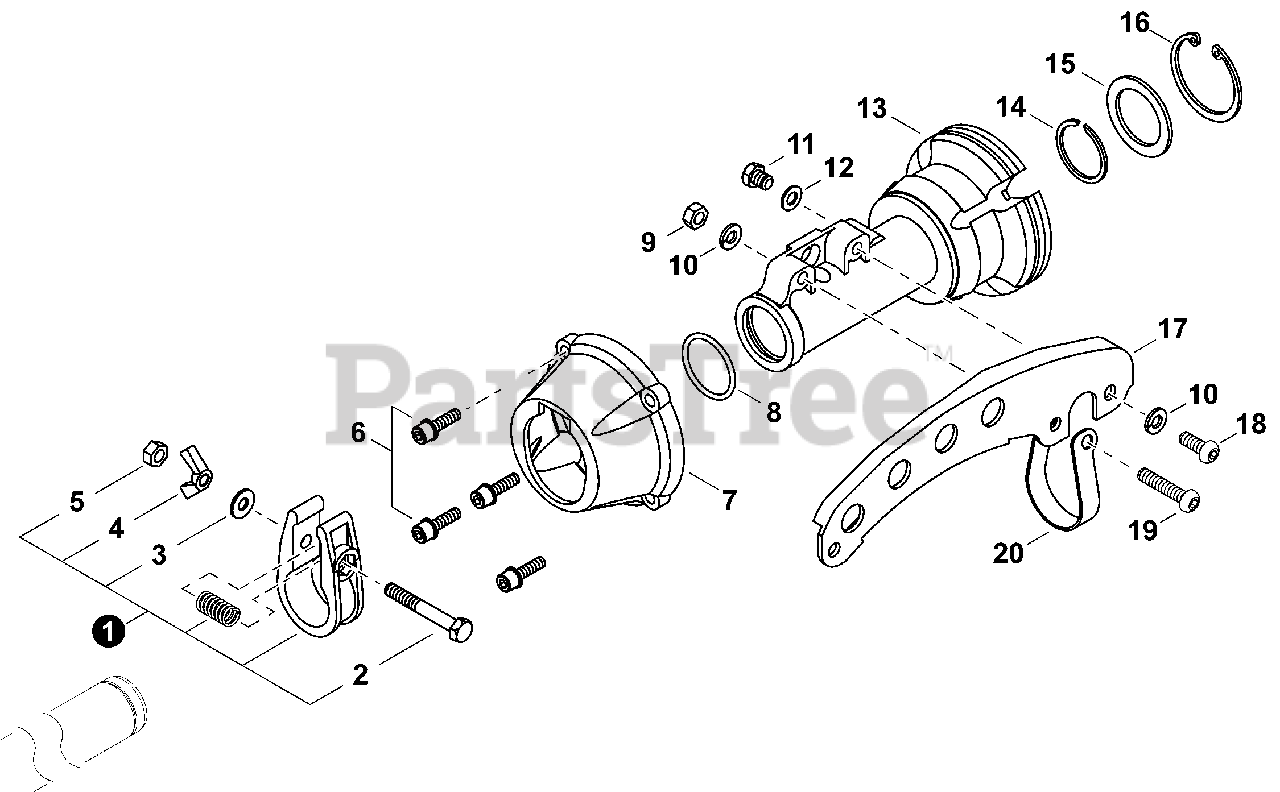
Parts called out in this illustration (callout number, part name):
1	SWIVEL ASSY
3	WASHER 6MM
4	NUT, WING M6
5	NUT, LOCK M6
6	BOLT M5×20
7	CAP, CUSHION
9	NUT, HEX M6
10	WASHER, SPRING 6
11	BOLT M6×8
13	CUSHION, AV
14	RING, SNAP
15	STOPPER
16	RING, SNAP Ø40
18	BOLT M6×16
19	BOLT M6×30
